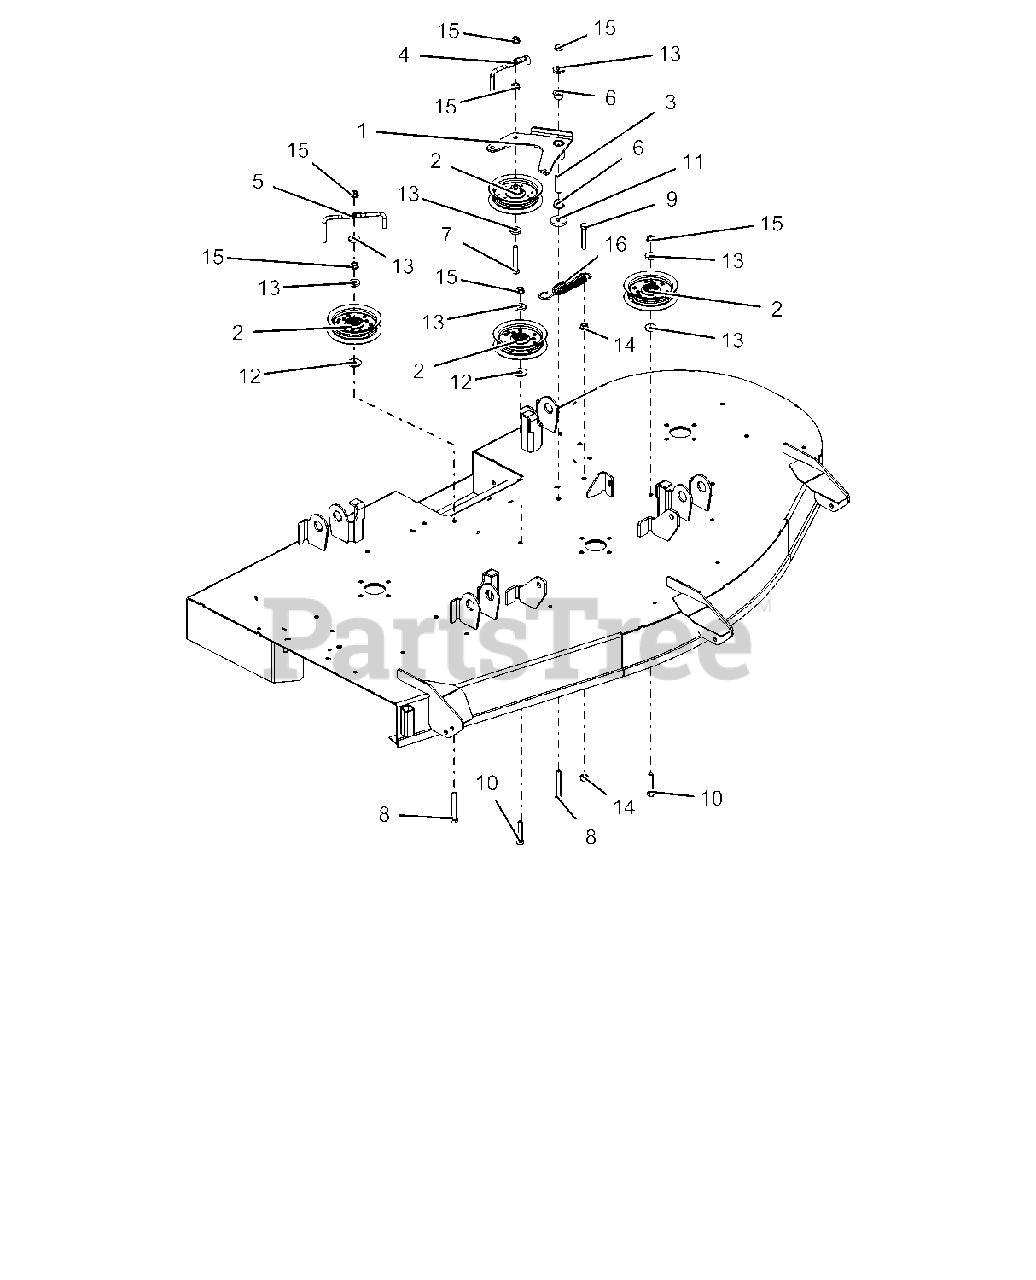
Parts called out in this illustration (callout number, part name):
1	WLDMT, IDLER ARM (RED)
2	ASM, IDLER 4"
3	SPCR, .375IDX.625ODX1.66 PM
4	WIREFORM, BELT FINGER-RED
5	FINGER, BELT (RED)
6	BSHG, FLANGE .625 x .75 x .50 x 1.00
7	BLT-HEX .38-16X2.50 GR5 YWZC
8	BLT-HEX .38-16X2.75 GR5 YWZC
9	BLT-HEX .38-16X2.25 GR5 YWZC
10	BLT-HEX .38-16X2.00 GR5 YWZC
11	WSHR-FL-STL .406X1.50X.245 YWZC
12	WSHR-FL-STL .406X1.25X.10 YWZC
13	WSHR-FL-STL .406X1.00X.188 YWZC
14	@NUT-SPNLK-FLG .375-16 YWZC
15	NUT, LK-TOP-FLG .38-16 YWZC
16	SPRG, EXTENSION
